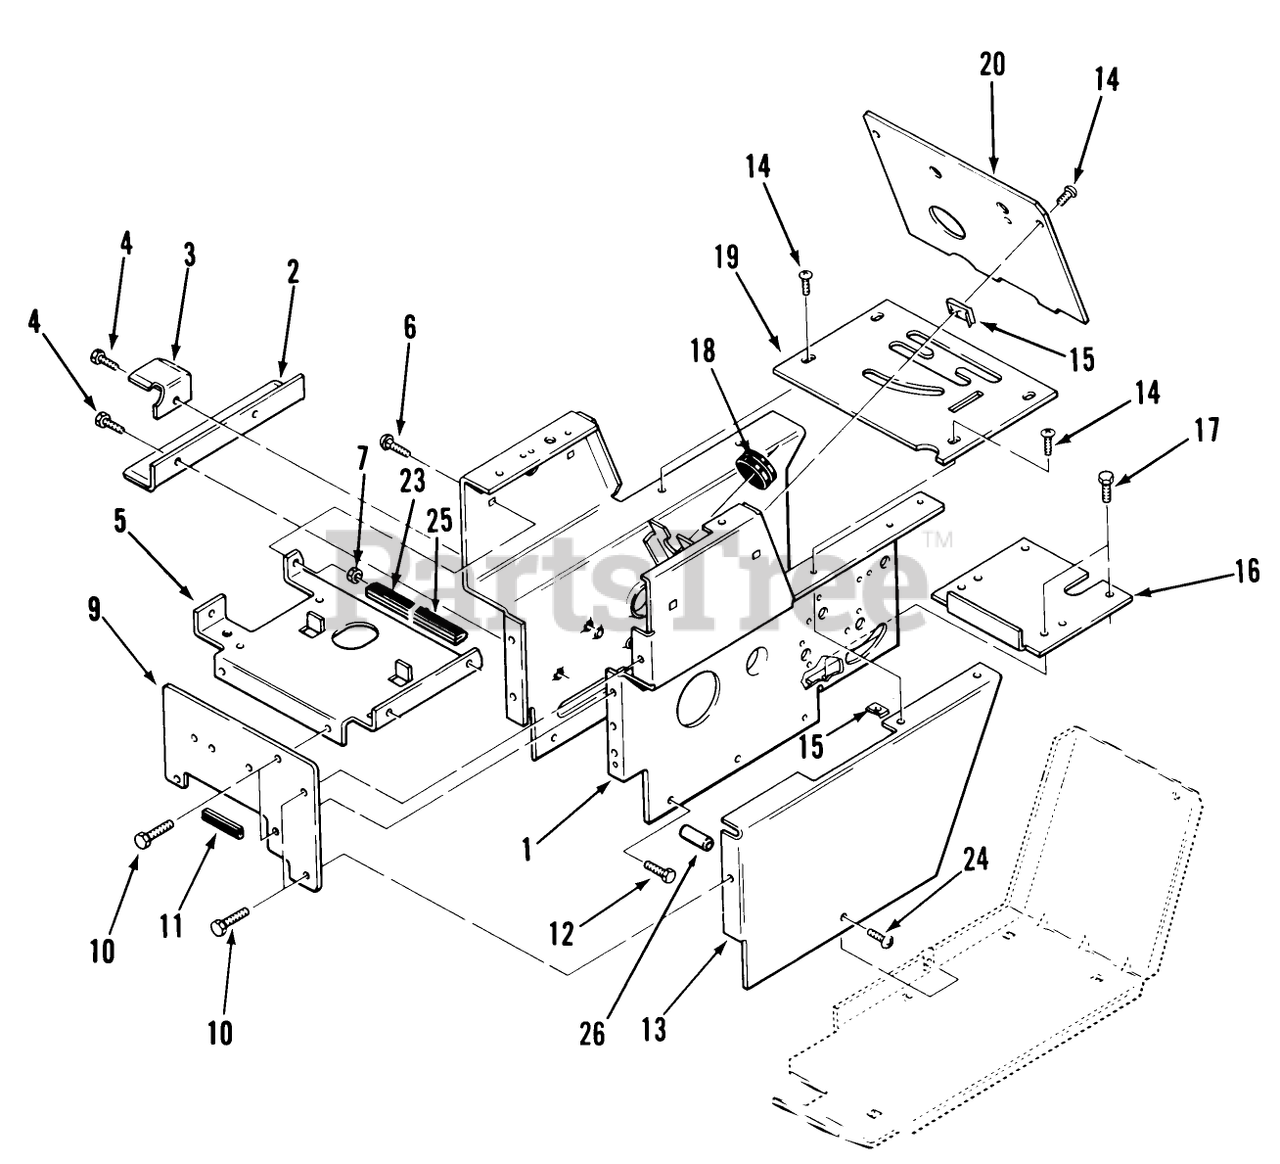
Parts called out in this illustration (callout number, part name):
2	ANGL-BLT GURD*B
3	BRCKET-BLT SUT*B
4	SCREW
10	SCREW
12	SCREW
14	SCREW-PPH
17	SCREW
18	GROMMET
26	Spacer 417-8 Only
